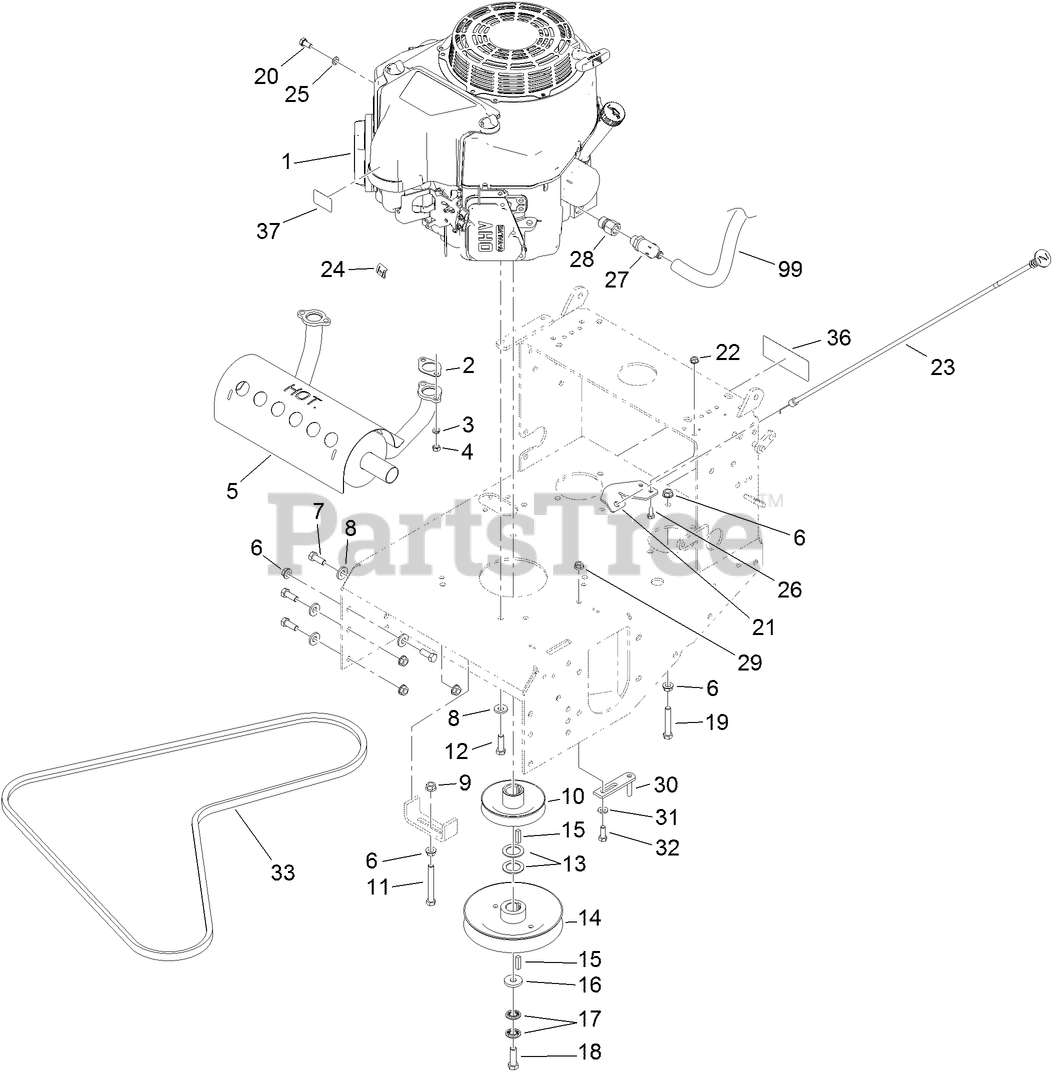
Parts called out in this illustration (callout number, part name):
2	GASKET-EXHAUST
3	WASHER-LOCK
5	MUFFLER-HORIZONTAL, OFFSET
6	NUT-HHF, WHIZ
7	SCREW-HH
8	WASHER-BELLEVILLE
9	NUT-HF
10	PULLEY
11	SCREW-HH
12	SCREW-HH
13	WASHER-SPACER
14	PULLEY ASM
16	WASHER
17	WASHER-SPRING
18	SCREW-HH
19	SCREW-HH
20	SCREW-HH
21	Bracket-Cable, Choke
22	NUT-HF
23	Cable-Choke
24	CLAMP-CABLE
25	WASHER-LOCK
26	SCREW-HH
27	VALVE-DRAIN, OIL
28	Adapter
29	NUT-HF
30	GUIDE-BELT
31	WASHER-SPRING
32	SCREW-HH
33	BELT-V
36	DECAL-CAUTION
37	DECAL-CAUTION
99	HOSE-DRAIN, OIL
